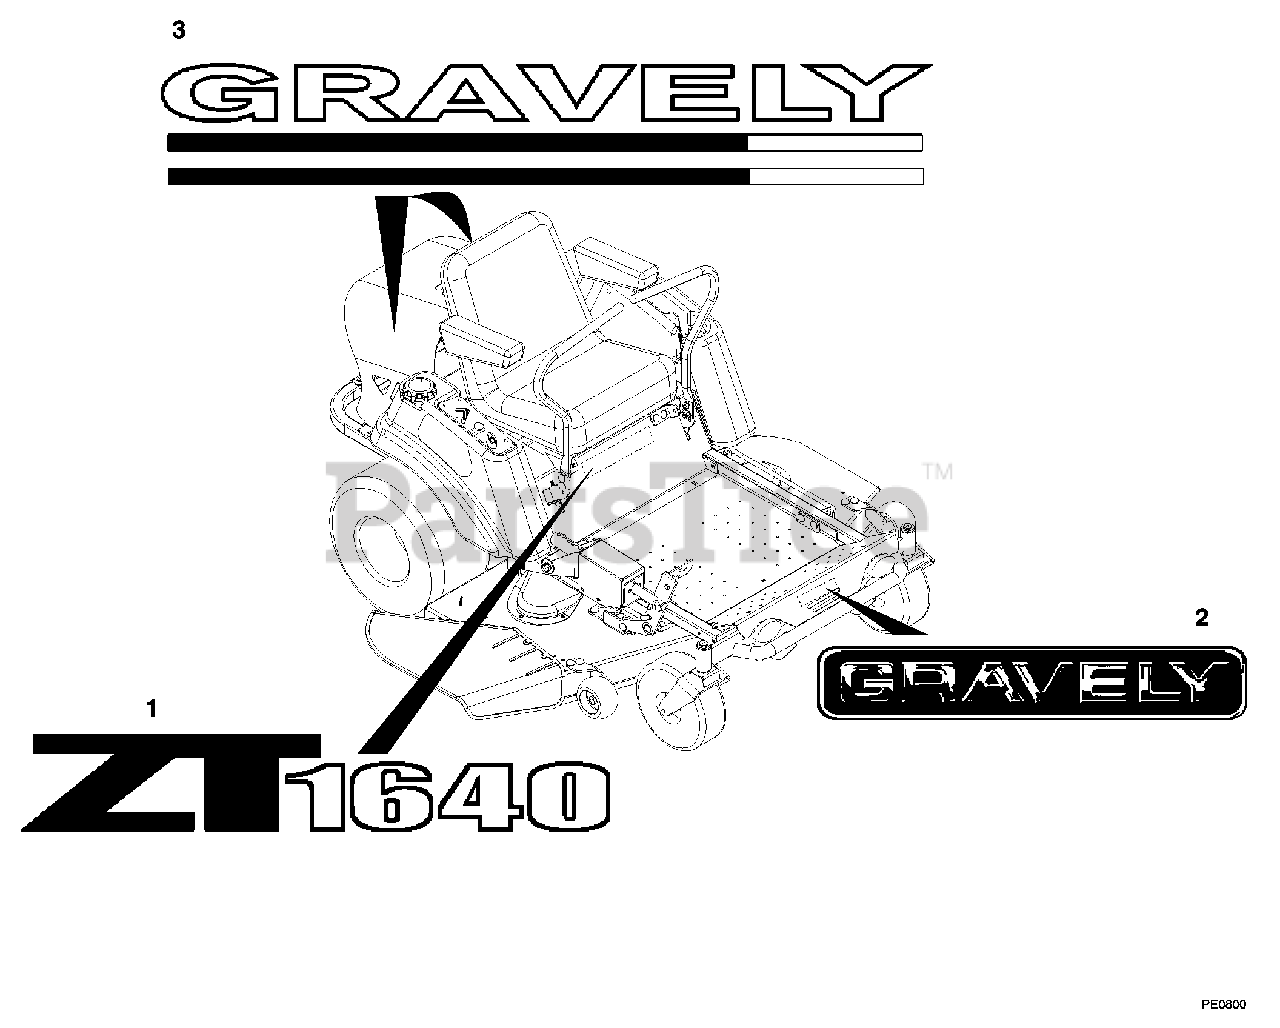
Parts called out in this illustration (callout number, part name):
1	Decal ZT 1640 (034)
1	Decal-ZT 1844 (036)
1	Decal-ZT 2048 (038)
1	Decal-ZT 2252 (040)
2	Decal-Gravely Jewel
3	Decal, ZT Hood
